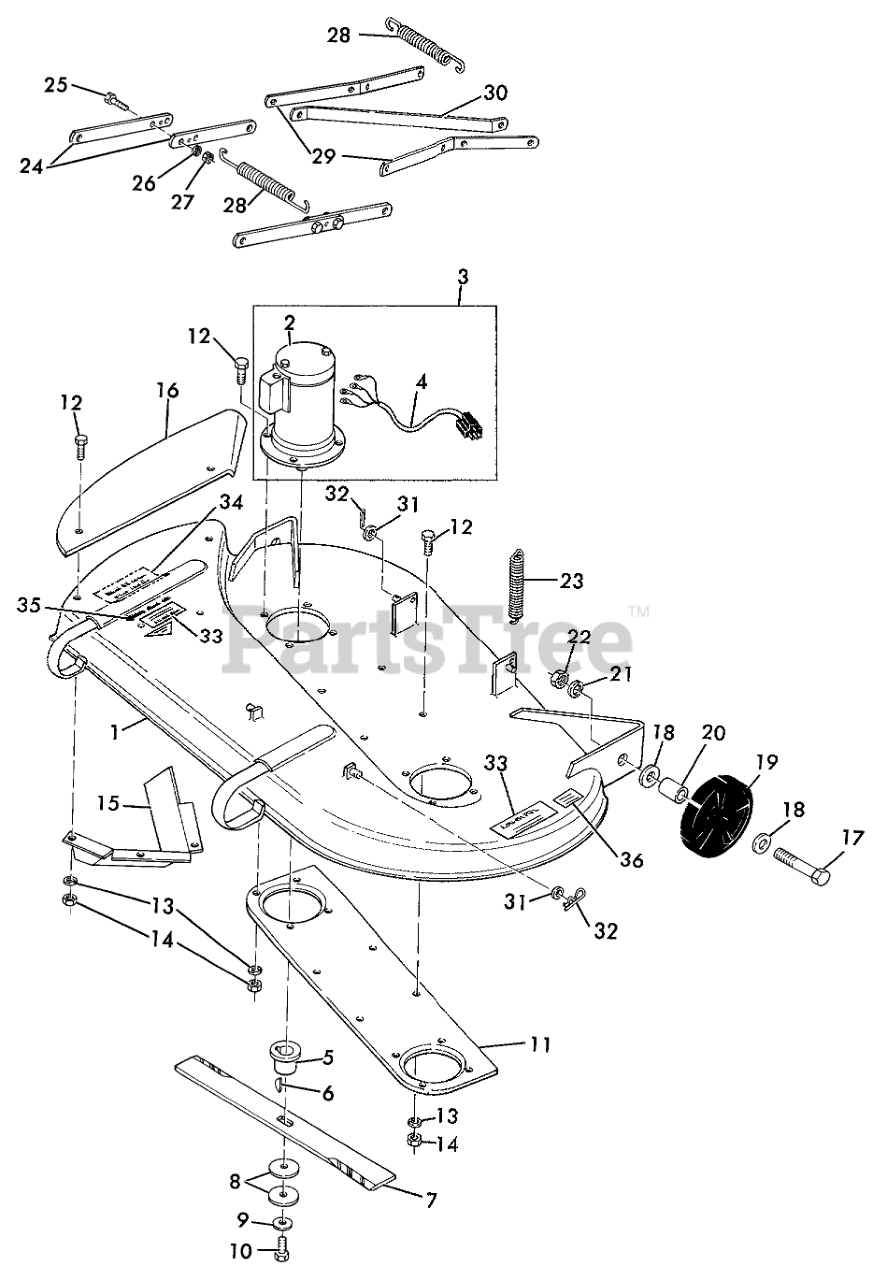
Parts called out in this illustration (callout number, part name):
1	Housing Assembly
2	Motor & Wiring Harness Assembly
3	Motor
4	Wiring Harness
5	Clutch, Mower Blade
6	Key, Woodruff
7	Blade, Mower
8	Fiber Washer
9	Washer, Clutch
10	Cap Screw, Self Locking 3/8-24 x 1 1/4
11	Stiffener Plate
12	Bolt, 1/4-20 x 5/8
13	Lockwasher, 1/4
14	Nut, 1/4-20
15	Baffle
16	Chute Extension
17	Bolt, Hex 3/8-16 x 2 3/4
18	Washer-3/8
19	Wheel
20	Bushing
21	Lockwasher 3/8
22	Nut, Hex 3/8-16
23	Spring, Lift
24	Mower Arm, Front
25	Carriage Bolt, 5/16-18 x 1
26	Lockwasher-5/16
27	Cotter Pin
28	Spring, Mower Arm
29	Mower Arm, Rear
30	Stabilizer Bar
31	Washer, 1/2
32	Cotter Pin 1/8 x 1
33	Decal-Caution
34	Decal-Caution
35	Decal-Edge of Cut
36	Decal, Mower Height Adj.
